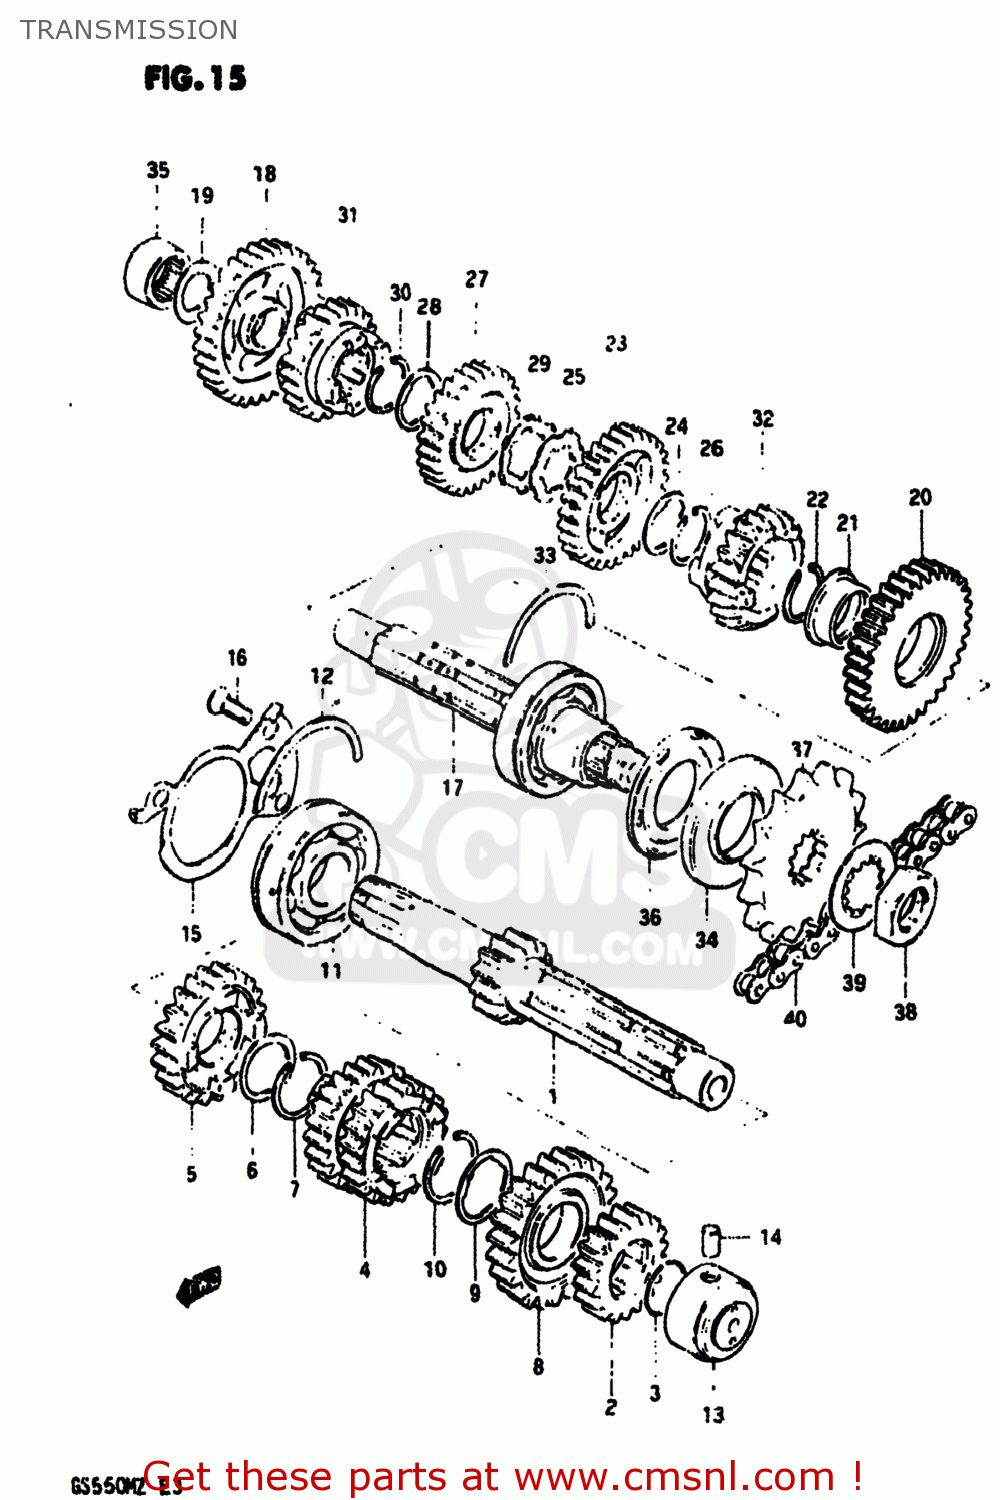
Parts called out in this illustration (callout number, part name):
1	SHAFT,COUNTER
2	GEAR,SECOND DRIVE
3	RING,SNAP
4	GEAR,THIRD DRIVE
5	GEAR,FIFTH DRIVE
6	WASHER
7	CIRCLIP
8	GEAR,SIXTH DRIVE
9	WASHER,LOCK
10	CIRCLIP
11	BEARING(25X62X17)
12	C-RING
13	BEARING
14	PIN
15	PLATE,COUNTERSHAFT BEARING
16	SCREW
17	SHAFT,DRIVE
18	GEAR,FIRST DRIVEN
19	WASHER
20	GEAR,SECOND DRIVEN
21	BUSHING
22	CIRCLIP
23	GEAR,THIRD DRIVEN
24	WASHER,LOCK
25	WASHER,LOCK
26	CIRCLIP
27	GEAR,FOURTH DRIVEN
28	WASHER,LOCK
29	WASHER
30	CIRCLIP
31	GEAR,FIFTH DRIVEN
32	GEAR,SIXTH DRIVEN
33	C-RING
34	SEAL,OIL(32X62X7)
35	ROLLER BEARING (20X34X1
36	SEAL,OIL(32X62X5.5)
37	SPROCKET,ENGINE
38	NUT
39	WASHER
40	CHAIN ASSEMBLY,DRIVE
